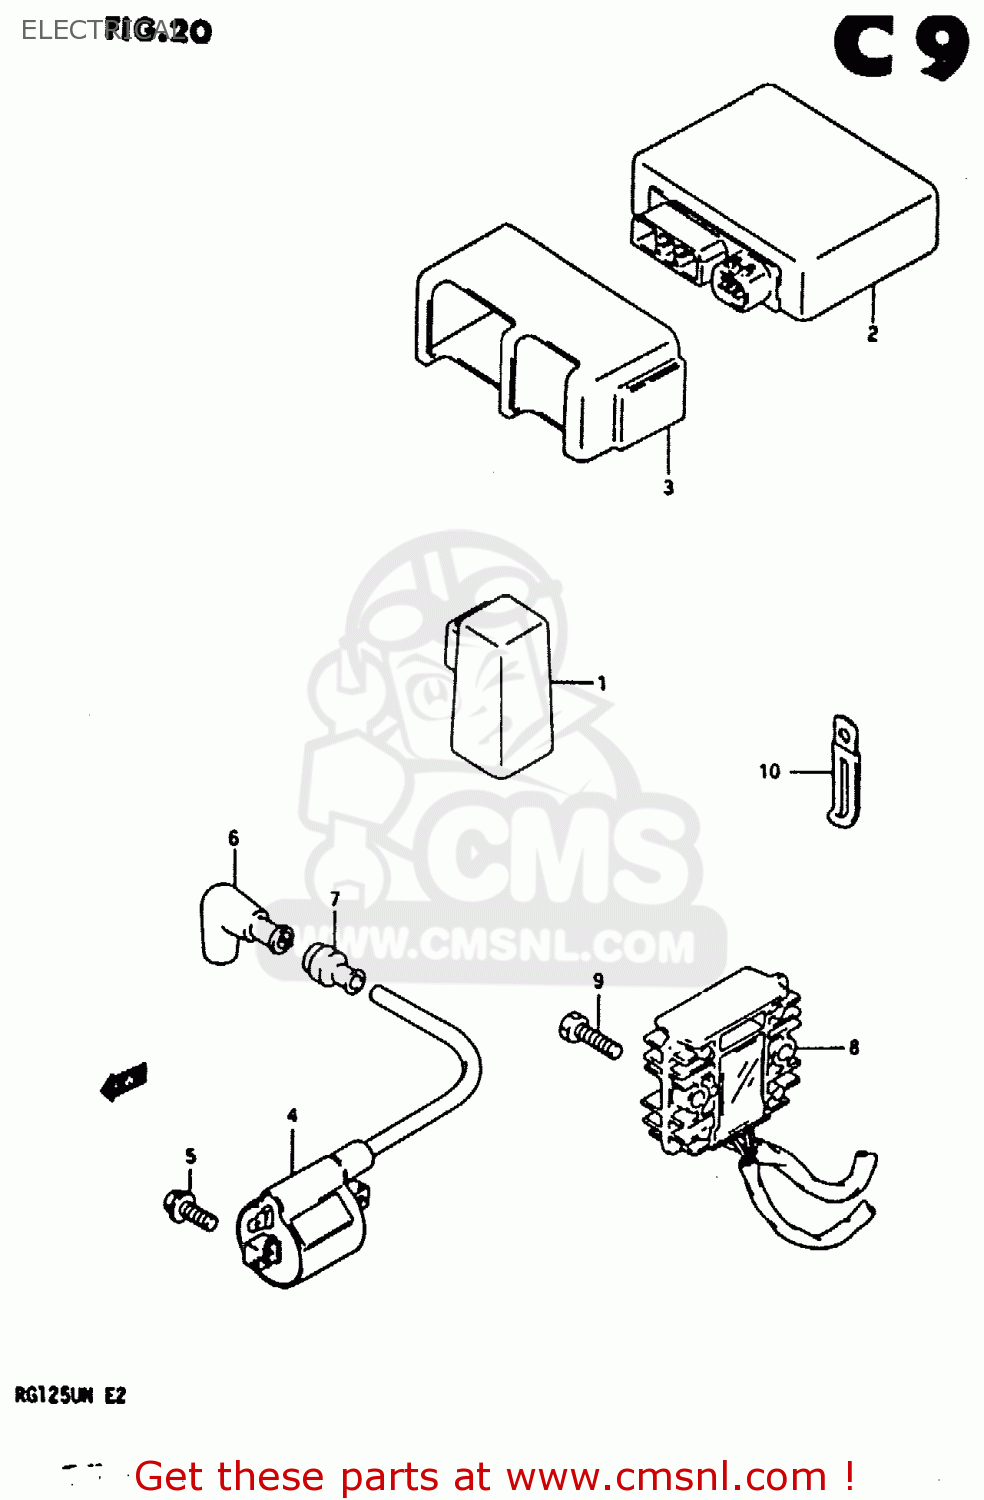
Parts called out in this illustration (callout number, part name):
1	RFLAY ASSY, STARTING MOTOR
2	CDI UNIT
3	HOLDER, CDI UNIT
4	COIL ASSY,IGNITION
5	BOLT
6	CAP,SPARK PLUG
7	SEAL,HIGH TENSION CORD
8	RECTIFIER ASSY
9	SCREW (6X25)
10	CLAMP
